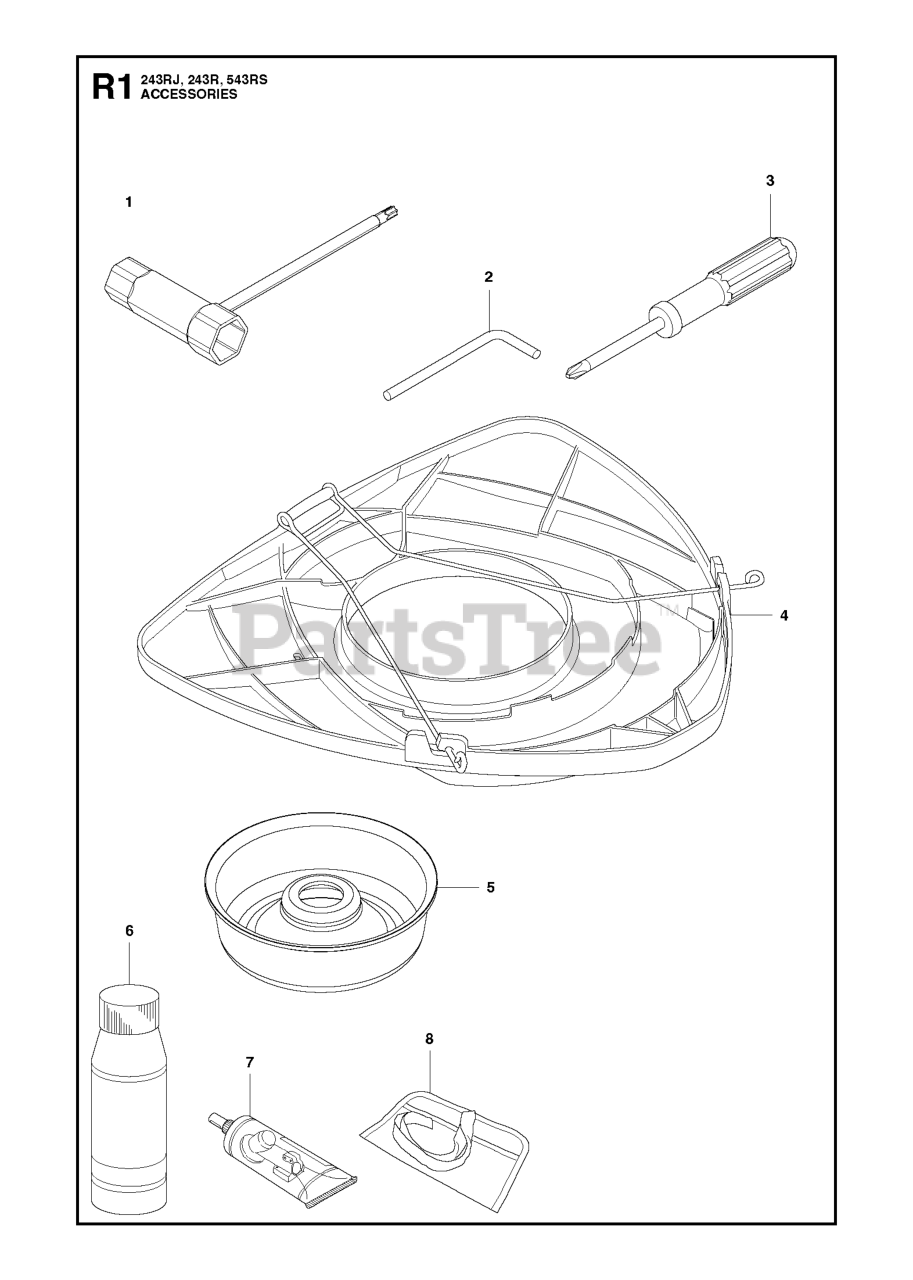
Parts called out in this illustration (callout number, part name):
4	TRANSPORT GUARD
5	SUPPORT CUP
6	Air Filter Oil 1l.
7	BEVEL GEAR GREASE
